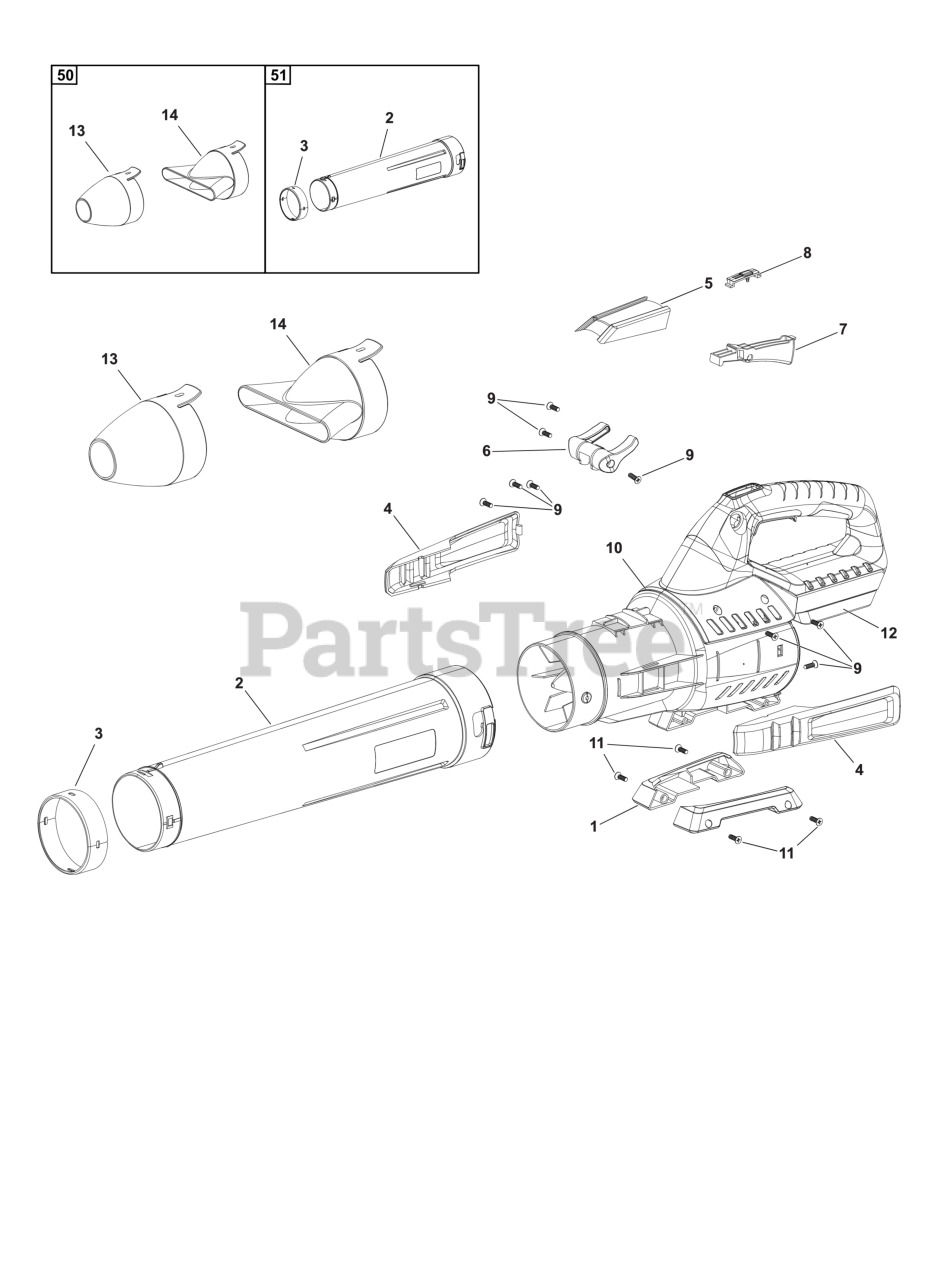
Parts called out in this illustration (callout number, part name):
1	Kit, 18V Jet Blower Feet
2	JET BLOWER TUBE
3	METAL RING
4	SNAPPER SIDE INSERT
5	SNAPPER TOP INSERT
6	SPEED CONTROL KNOB
8	TURBO BUTTON
9	SCREW 4MM X 16MM PHILLIPS SELF TAP
10	18V JET BLOWER POWER HEAD
11	SCREW M4 X 14
12	SINGLE BATTERY BRACKET
13	ROUND NOZZLE
14	FLAT NOZZLE
50	TUBE & STEEL RING
51	ROUND & FLAT NOZZLES
